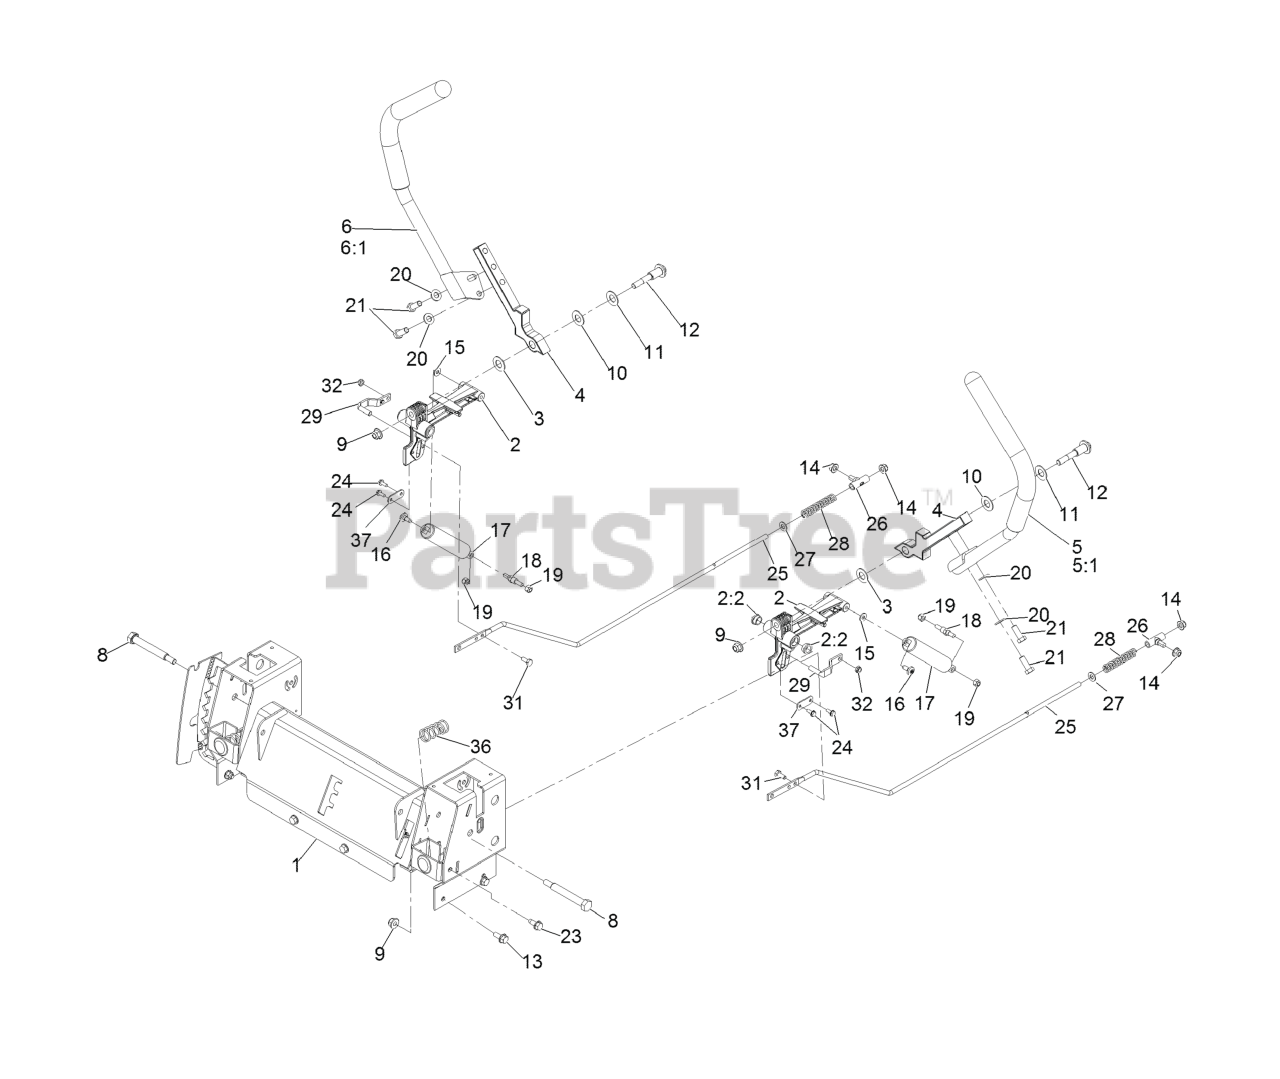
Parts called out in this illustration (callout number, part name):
1	CONTROL-BOX
2	ACTUATOR ARM ASM
2:2	BUSHING-FLANGE
3	WASHER-NYLON
4	ARM-CONTROL
5	HANDLE-CONTROL, LH
6	HANDLE-CONTROL, RH
8	BOLT-PIVOT
9	NUT-HF, NI
11	WASHER-BELLEVILLE
12	BOLT-PIVOT
13	SCREW-HHF
14	NUT-HF, NI
16	SCREW-SHOULDER
17	DAMPER-NON CAVITATING
18	STUD-DAMPER
19	NUT-LOCK, NI
20	WASHER-FLAT
21	SCREW-HH
23	Screw-HWH 5/16-18 X 3/4 Tf
24	SCREW-TAPTITE
25	Screw-HWH #10-24 X 1/2 Taptite
26	Rod-Hydro
27	WASHER-PLAIN
28	SPRING-RETURN, NEUTRAL
29	PIN-ROD, HYDRO
31	SCREW-HH
32	NUT-LOCK, NI
36	SPRING-RETURN
37	PLATE-STOP, HYDRO
